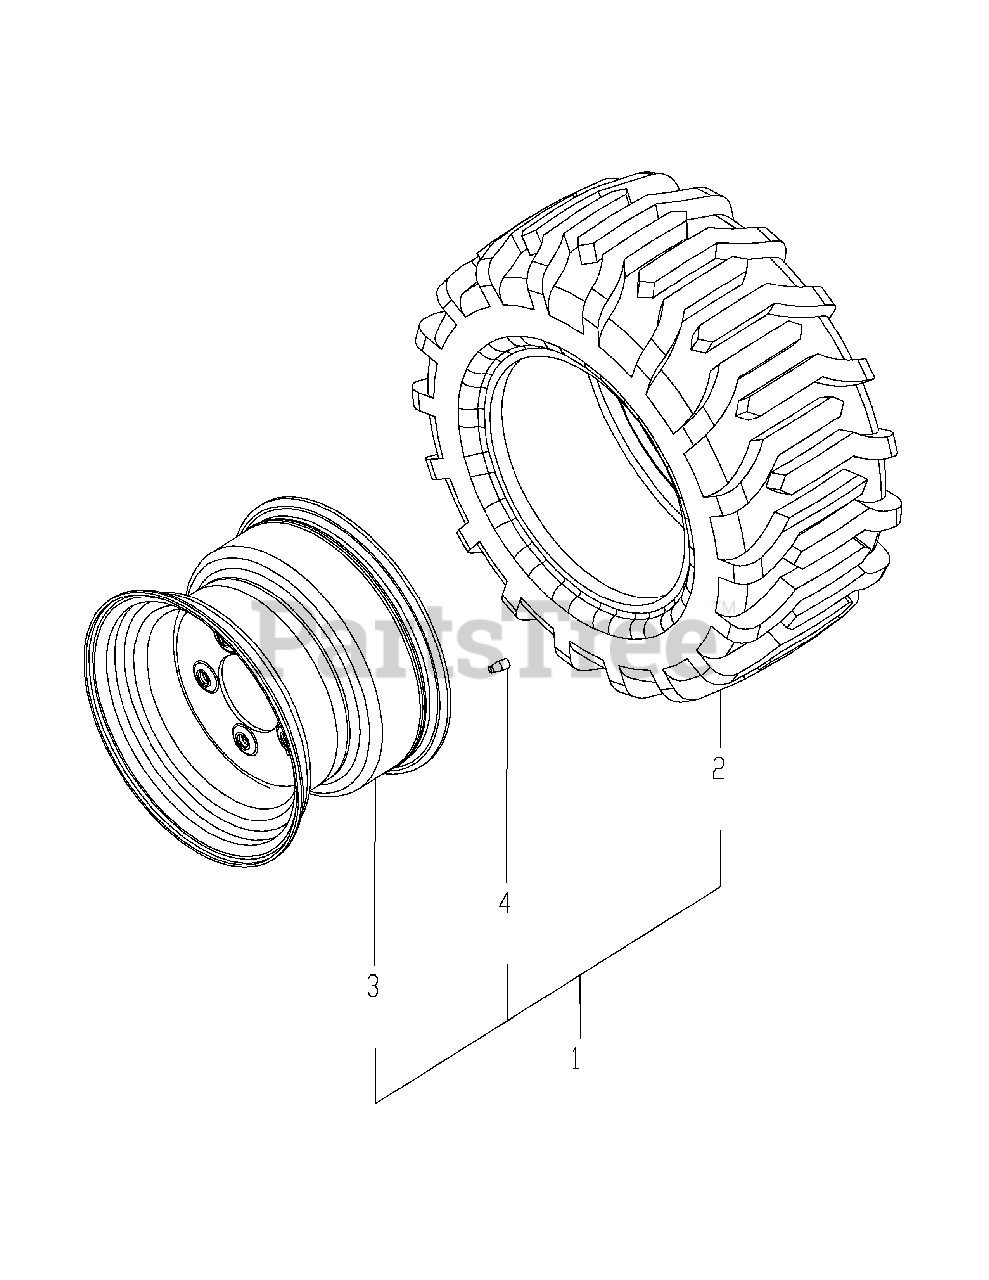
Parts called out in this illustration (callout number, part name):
1	TIRE ASM-FRNT IND LH
1	TIRE ASM-FRNT IND RH
2	TIRE, 18X8.5-10 R4
